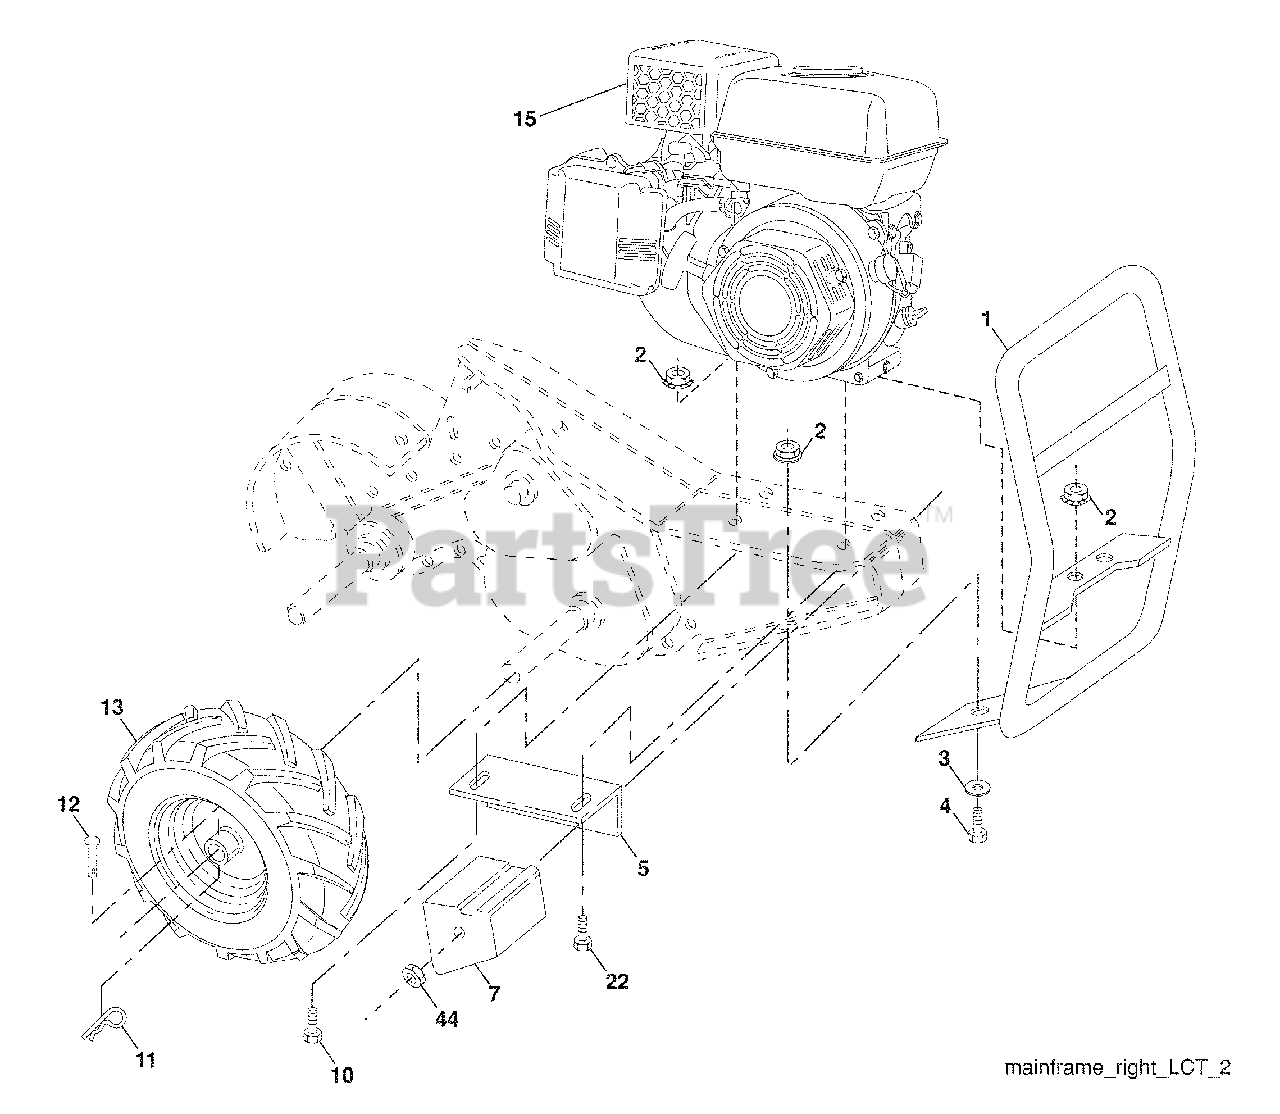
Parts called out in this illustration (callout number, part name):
1	Bumper Asm.
2	Locknut, Hex, Flange 5/16-18
3	Washer 11/32 x 11/16 x 16 Ga.
4	Bolt 5/16-18 x 3/4
5	Bracket, Reinforcement R.H.
6	Counter Weight, R.H.
7	Bolt, Hex 5/16-18 x 1-1/2
8	Clip, Hairpin
9	Rivet, Drilled
12	Tire Valve
14	Bolt 5/16-18 x 1-3/4
15	Nut Keps Hex 3/8-16 unc
